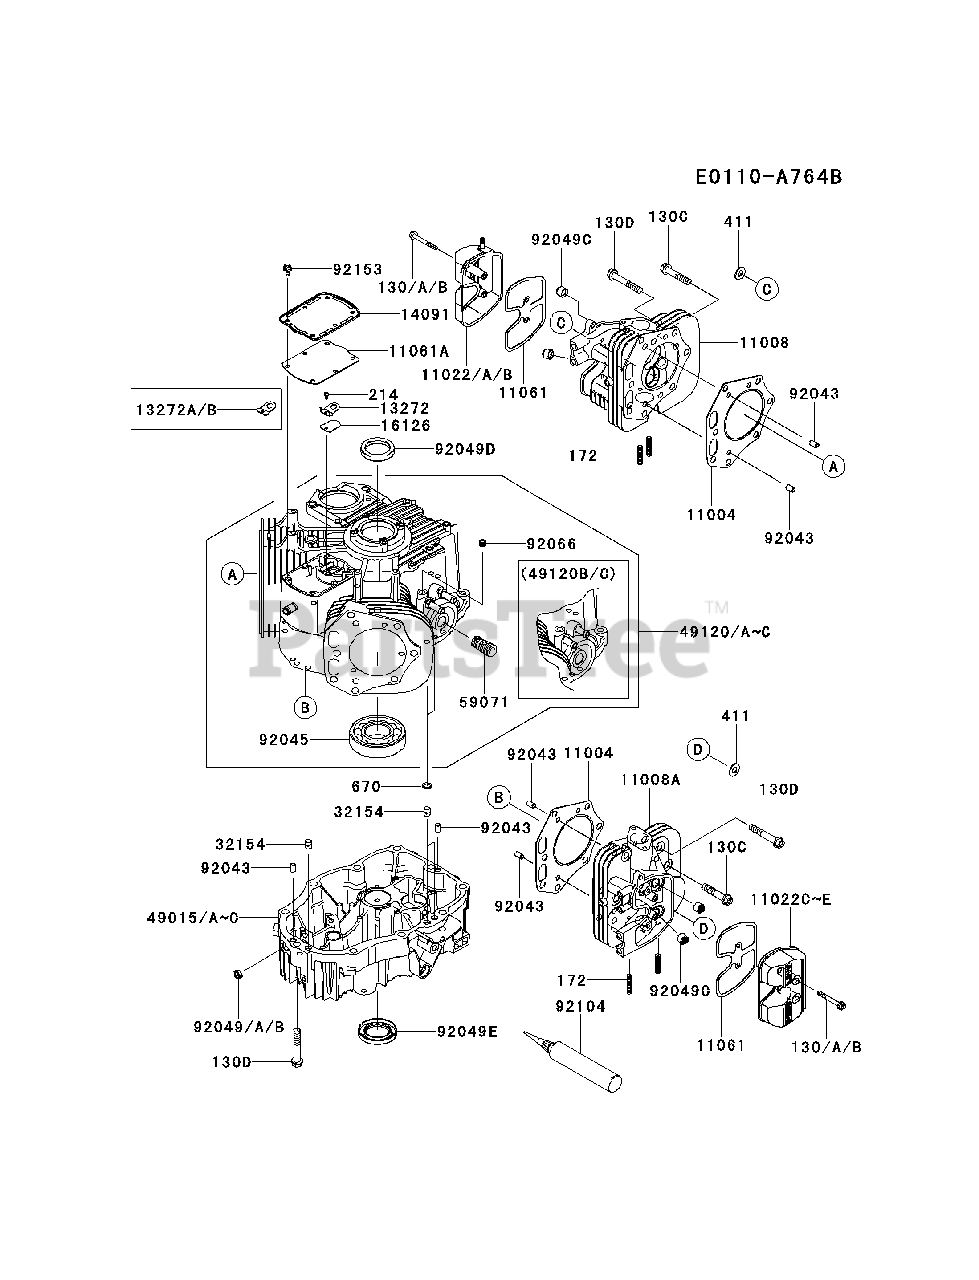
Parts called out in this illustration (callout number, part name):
130	BOLT-FLANGED,6X50
130B	BOLT-FLANGED,6X50
130C	BOLT-FLANGED,10X50
130D	BOLT-FLANGED,10X60
172	BOLT-STUD,8X18
214	SCREW-PAN+-,4X8
411	WASHER-PLAIN,10MM
670	O RING,11MM
